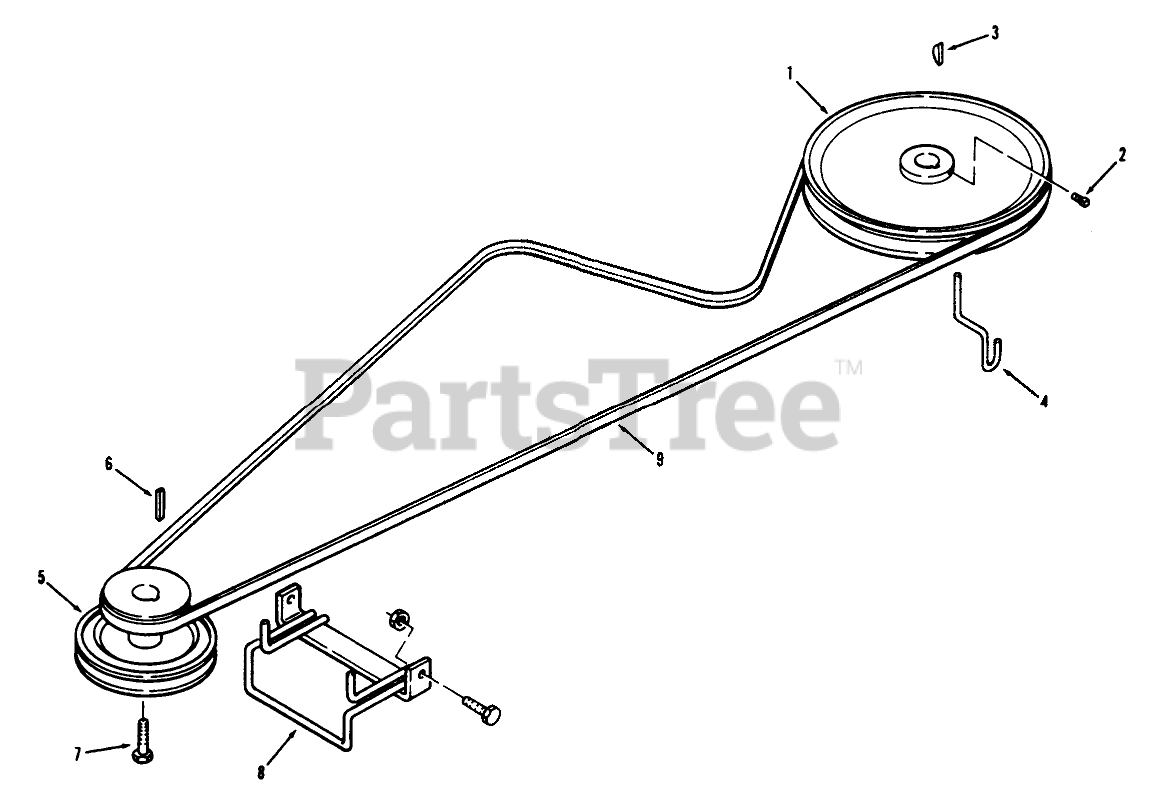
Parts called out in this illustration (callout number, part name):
1	Pulley-Transmission
2	Set Screw
3	KEY WOODRUFF
4	Belt Retainer
5	PULLEY-ENGINE
6	Key
7	HEX HD CAP SCREW
8	Assy-Belt Bracket
9	V-BELT, TRANSMISSION DR.
